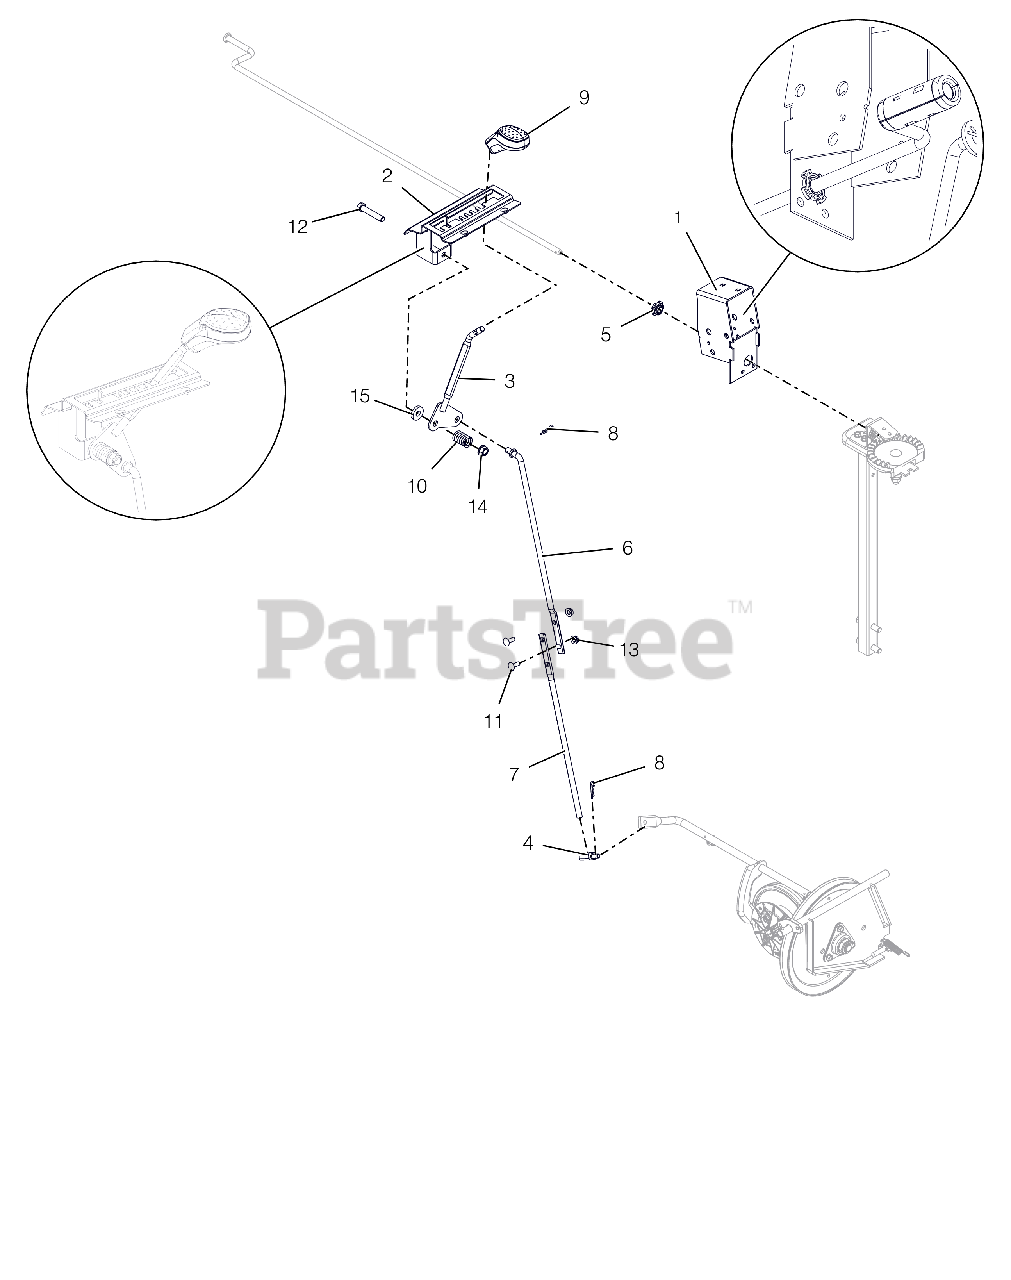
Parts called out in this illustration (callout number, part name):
1	WELDMENT, BRACKET INTERLOCK
2	WELDMENT, DETENT PLATE-COMPACT
3	LEVER, CONTROL-SHIFT(WELDMENT)
4	PIVOT,SHIFT ROD .375-16(TRUNN)
5	CRANK BUSHING, NYLON CHUTE BK
6	ROD, SHIFT - UPPER
7	ROD, SHIFT - LOWER(SMALL DASH)
8	PIN-HAIR INT .08X.18X1.18 YWZC
9	KNOB, CONTROL, DASH
10	SG-COMP .125X.781X1.250
11	@BLT-RDHDSQNK .25-20X.75 G5YZ
12	@BLT-HEX .38-16X2.00 GR5 YWZC
13	@NUT-LK-CTR-FLG .25-20 YWZC
14	@NUT-LK-TOP-FLG .38-16 YWZC
15	WSHR-FL-STL .406X1.00X.188 YWZ
